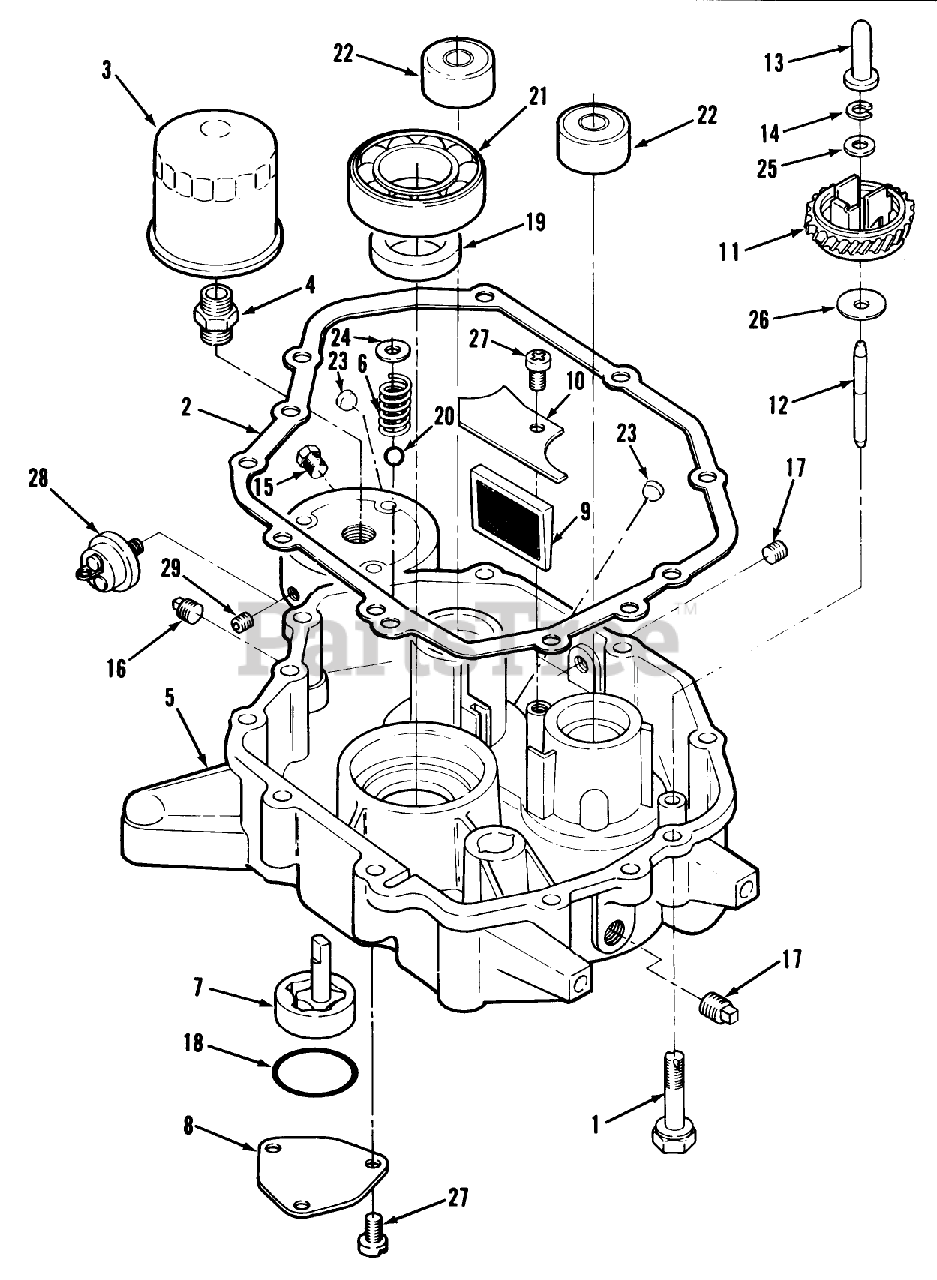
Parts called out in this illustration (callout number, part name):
1	SELF-TAP BOLT SP M8
4	ADAPTER
19	SEAL-OIL CRNKSHFT UP
28	SWITCH-OIL PRESSURE
